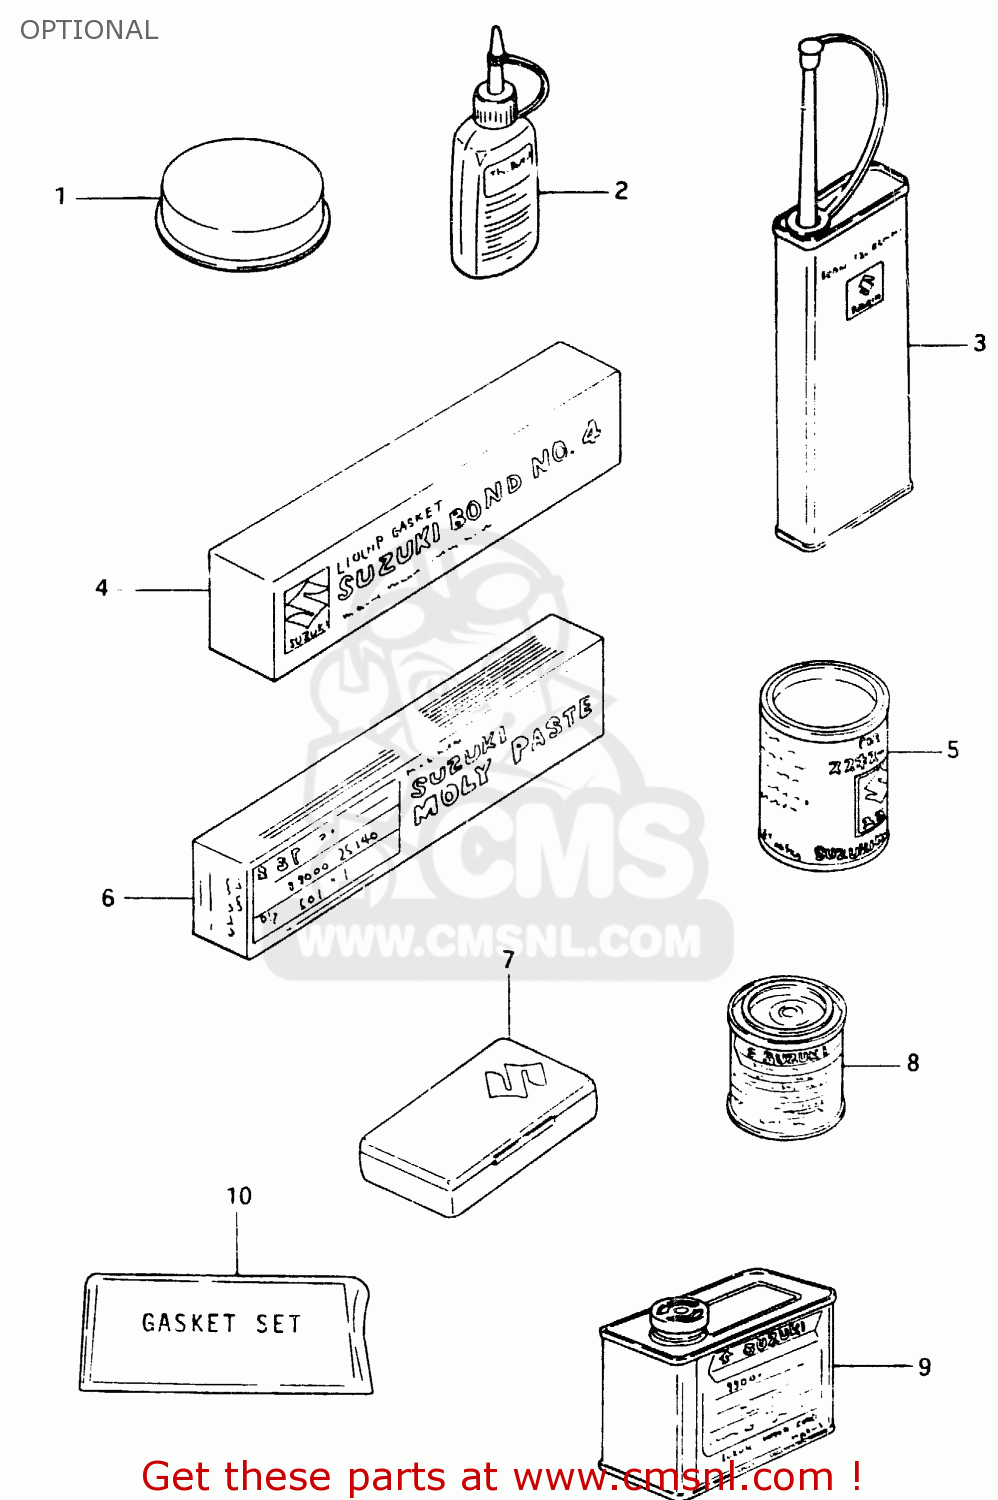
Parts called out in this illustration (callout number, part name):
1	GREASE,PBC FOR BRK PAD 20G
2	THREAD LOCK NO.1342
3	THREAD LOCK NO.1401 CLEAR 200G
4	BOND 1104
5	GREASE(C)EP2 LITHIUM 150G
6	SUZUKI MOLY PASTE
7	TUBE REPARING TOOL
8	PAINT,BLACK
9	PAINT (BLACK)
10	GASKET SET
